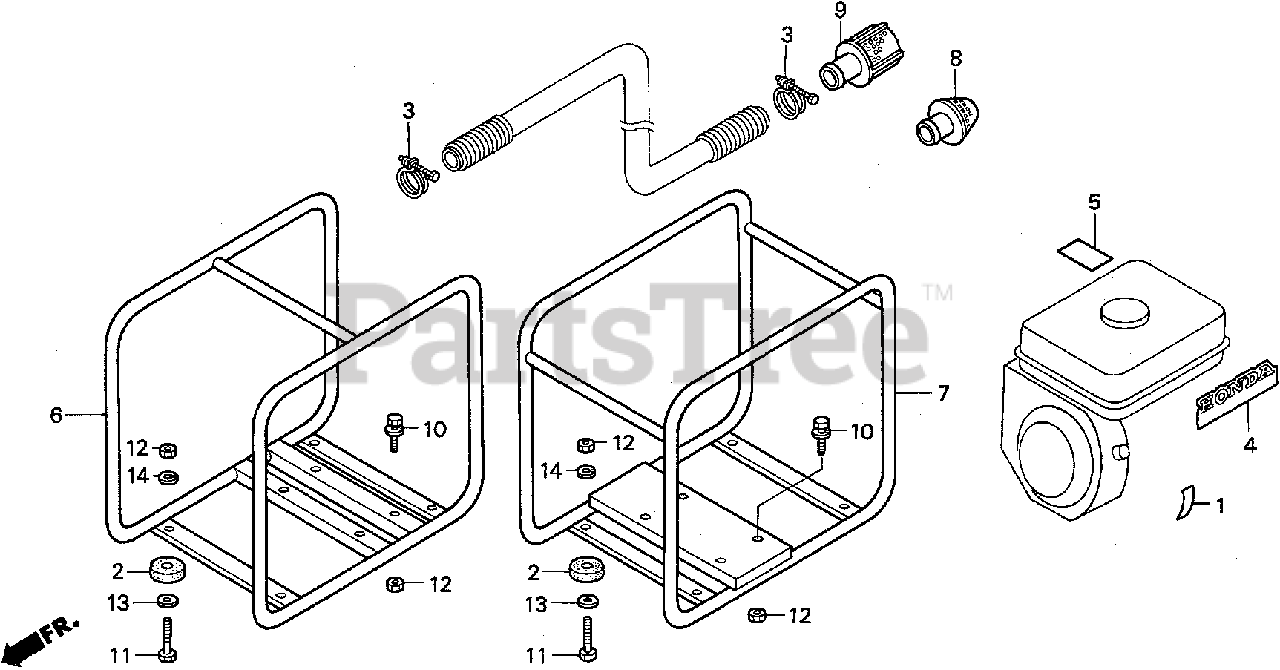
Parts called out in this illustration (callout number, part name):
2	RUBBER (LOWER)
3	BAND, HOSE
10	BOLT-WASHER (8X35)
11	BOLT, HEX. (8X20)
12	NUT, HEX. (8MM)
13	WASHER, PLAIN (8MM)
14	WASHER, SPRING (8MM)
